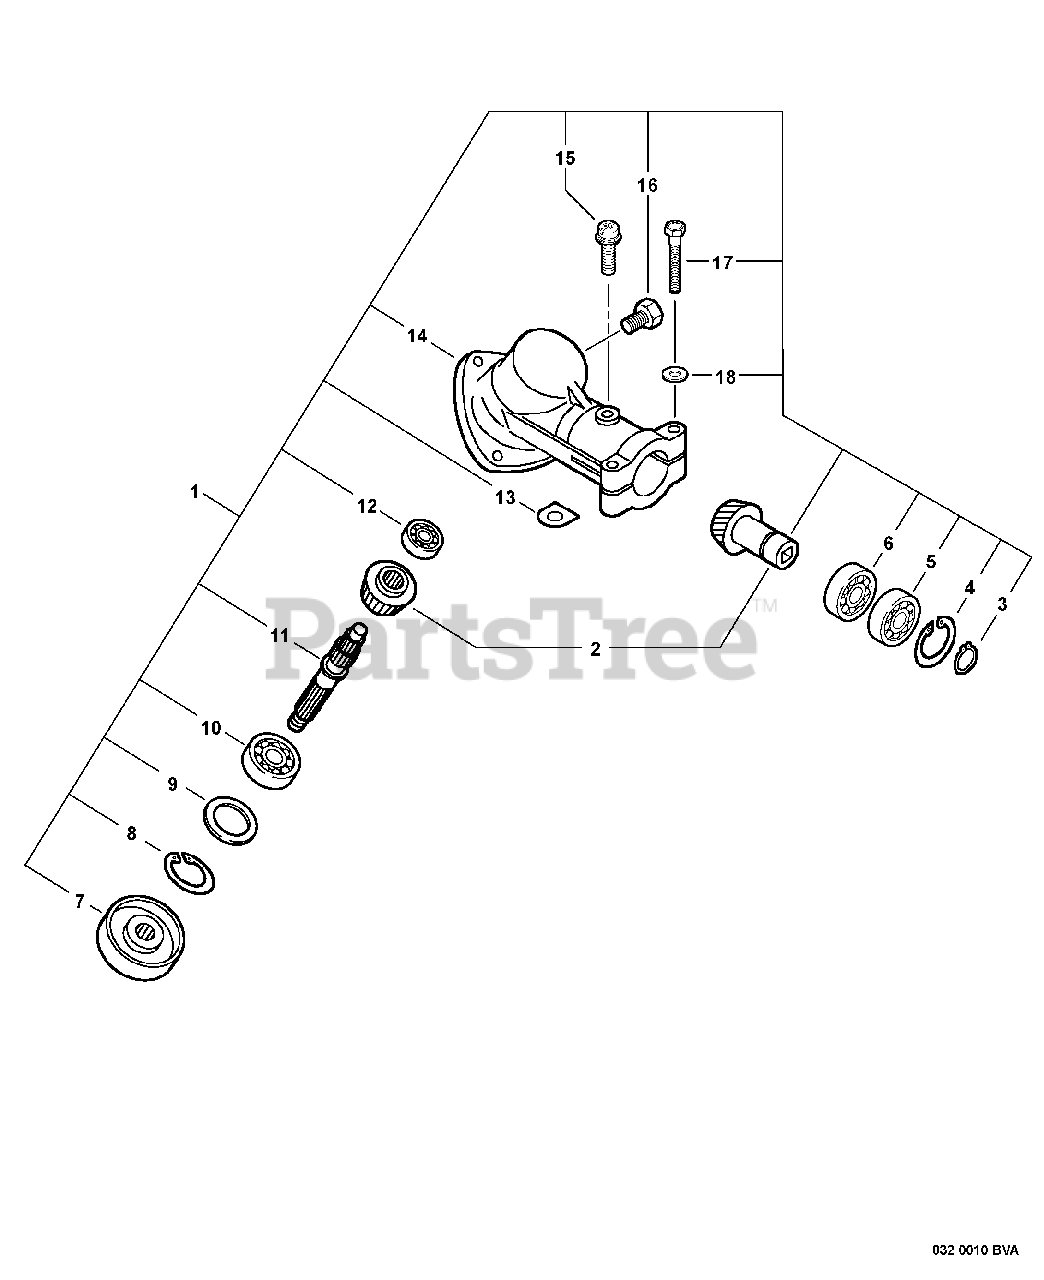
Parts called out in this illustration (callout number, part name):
1	GEAR CASE ASSY
2	GEAR SET
3	RING, SNAP Ø10
4	RING, SNAP Ø22
5	BEARING, BALL 6900Z
6	BEARING, BALL 6900
7	PLATE, ADAPTOR - UPPER
8	RING, SNAP Ø32
10	BEARING, BALL 6201
11	SHAFT, GEAR
12	BEARING, BALL 609
14	CASE, GEAR
15	SCREW 5×10
16	BOLT M8×8
17	BOLT 5×35 SP
18	WASHER, FLAT 5.5×10×0.8
